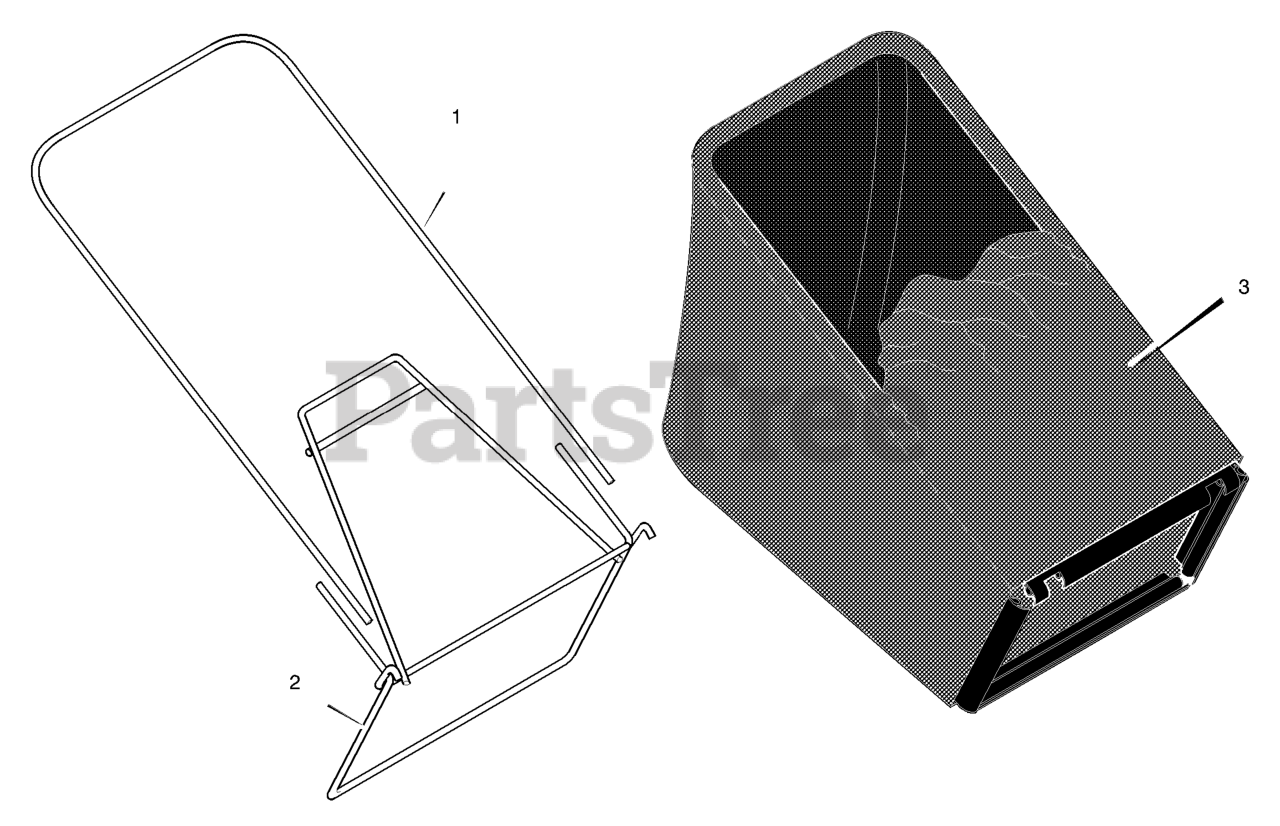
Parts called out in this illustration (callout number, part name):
1	Frame, Top
2	Frame Assembly
3	Bag, Cloth - Black
